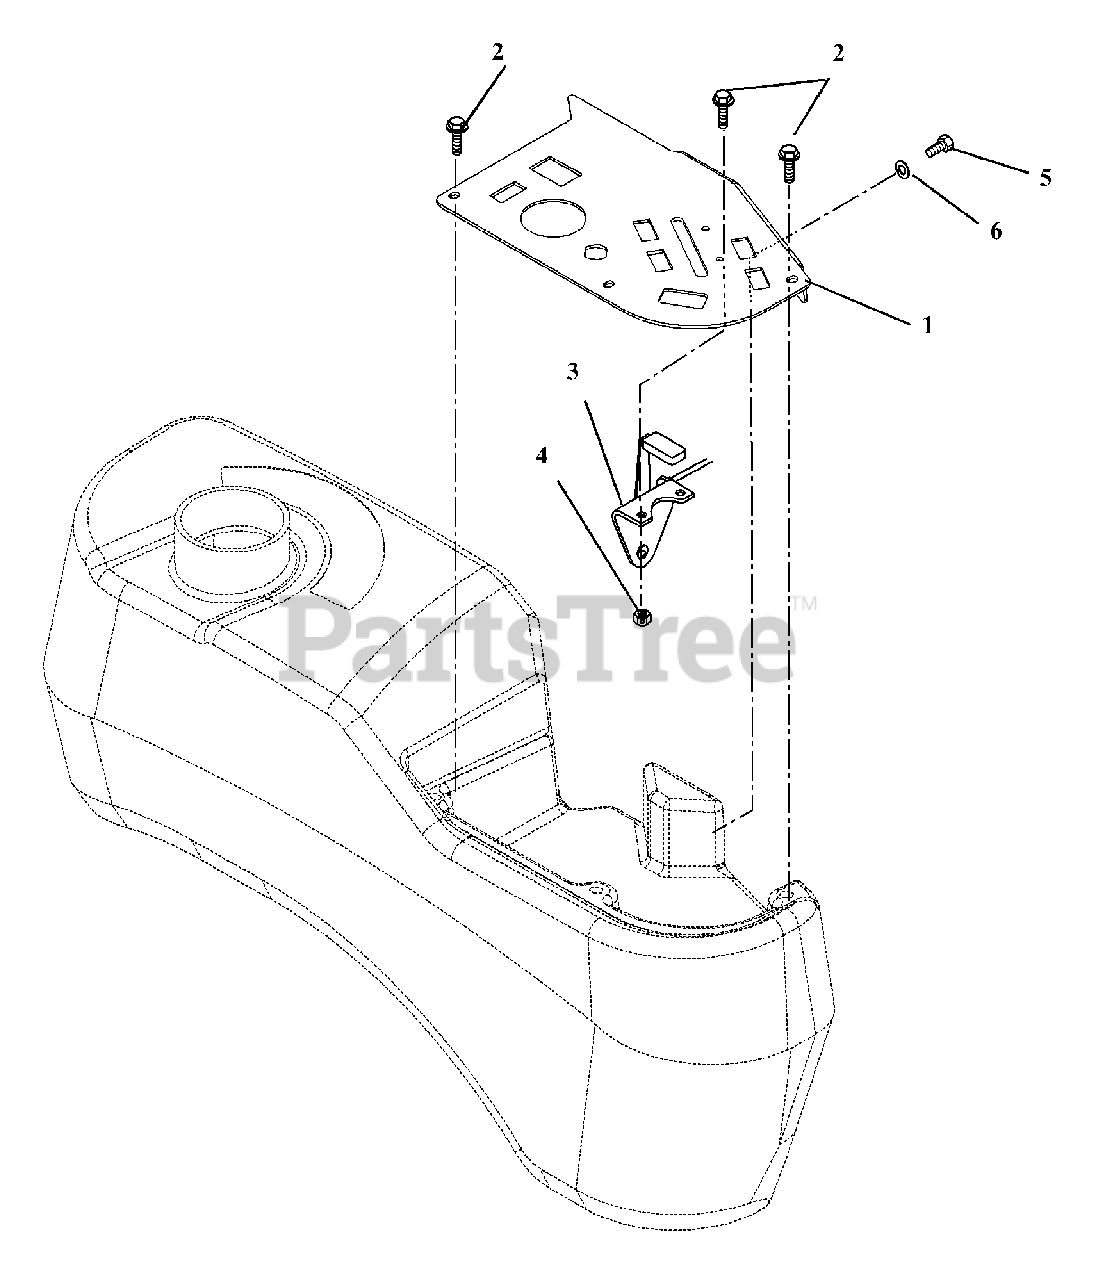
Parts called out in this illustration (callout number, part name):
1	PANEL, CONTROL MZ DIESEL BLACK
2	@SCR-MCH 10-24X.50 HWH YWZC
3	CABLE, THROTTLE-DIESEL
4	@NUT-LK-NYL 10-24 W/INSRT YWZC
5	@BLT-HEX .31-18X.75 GR5 YWZC
6	@WSHR-FL-STL.38X.875X.083 YWZC
